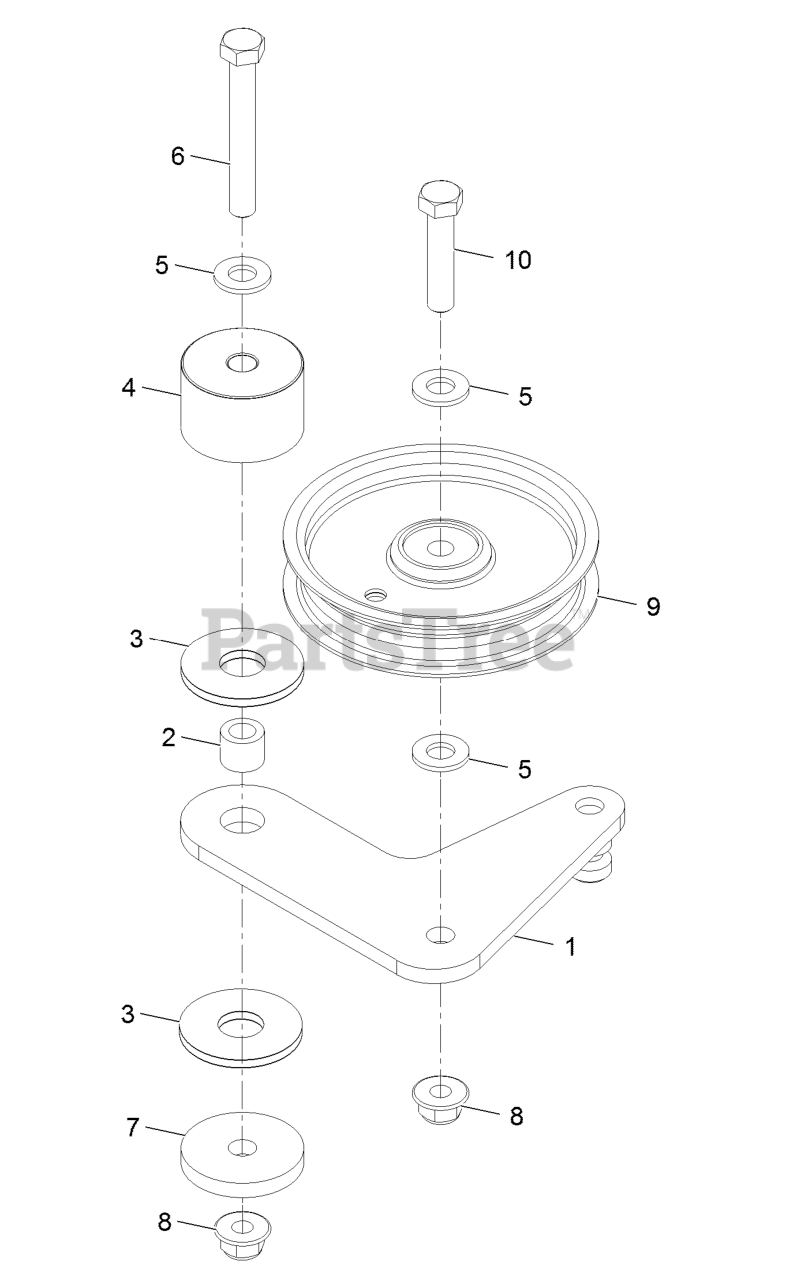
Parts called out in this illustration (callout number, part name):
1	PLATE-IDLER
2	BUSHING-LEVER, LIFT
3	WASHER-FRICTION, COMPOSIT
4	HUB, IDLER
5	WASHER-FLAT
6	SCREW-HH
7	WASHER-PLAIN
8	NUT-HF, NI
9	PULLEY-IDLER
10	SCREW-HH
